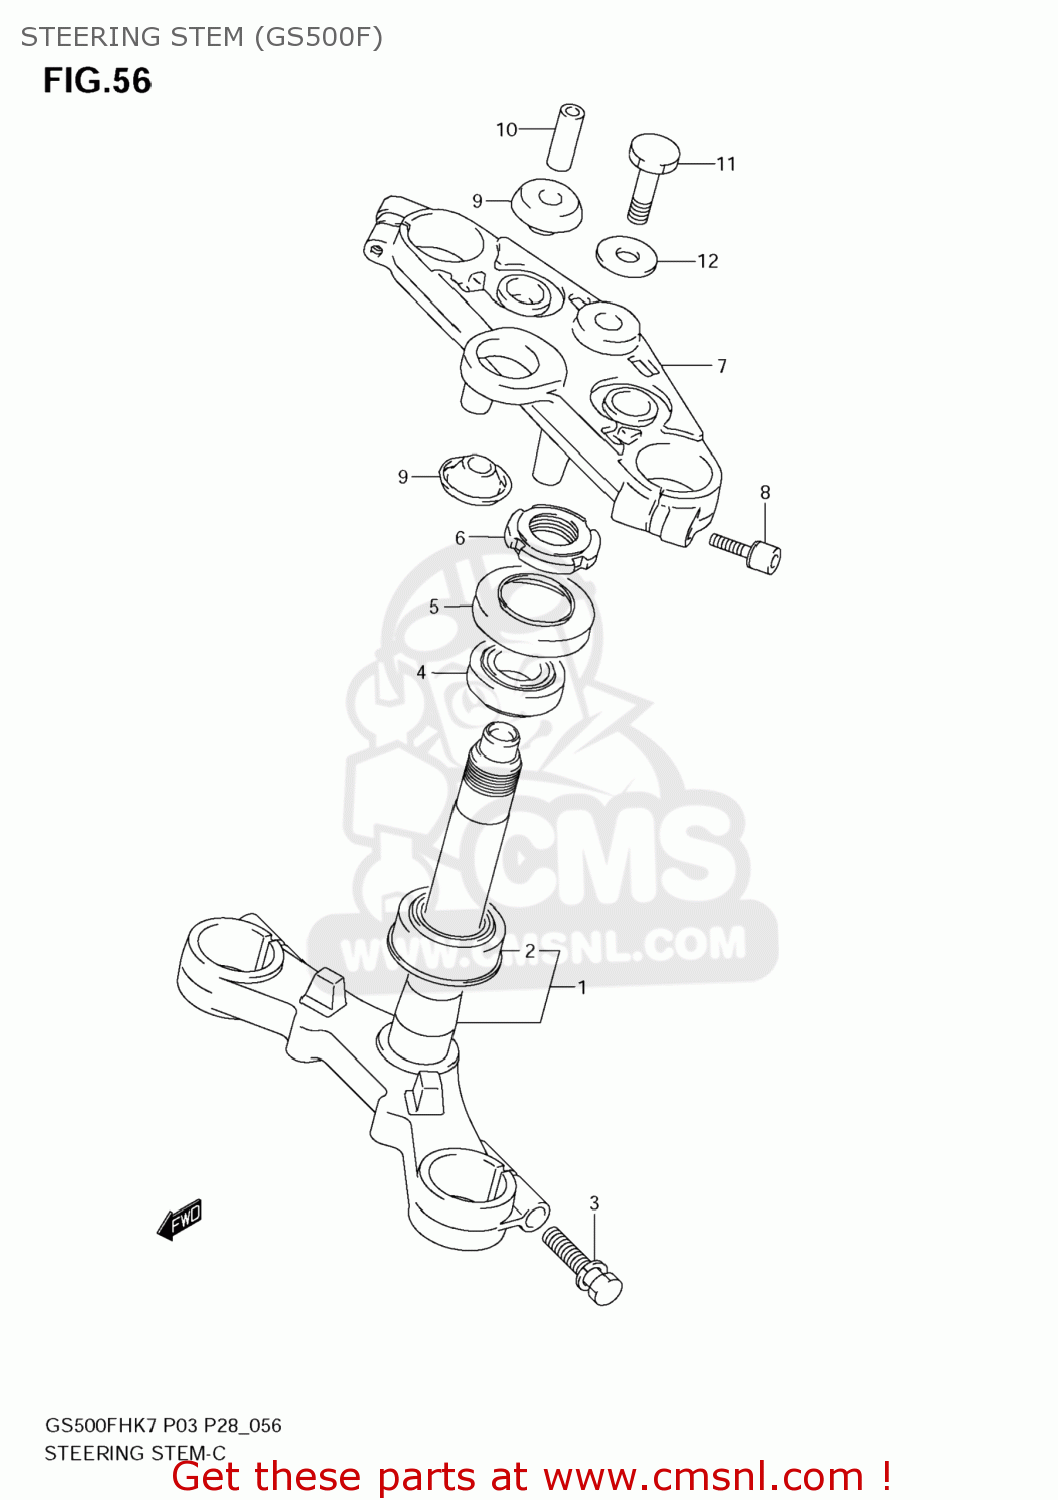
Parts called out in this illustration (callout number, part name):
1	STEM, STEERING
2	BEARING(30X55X17)
3	BOLT,STEERING
4	BEARING(25X47X15)
5	SEAL,STEERING UPR DUST
6	NUT,STEERING STEM(25X44X10)
7	HEAD STEERING
8	BOLT
9	CUSHION, STEM HEAD
10	SPACER, HEAD S
11	BOLT, UPPER
12	WASHER
